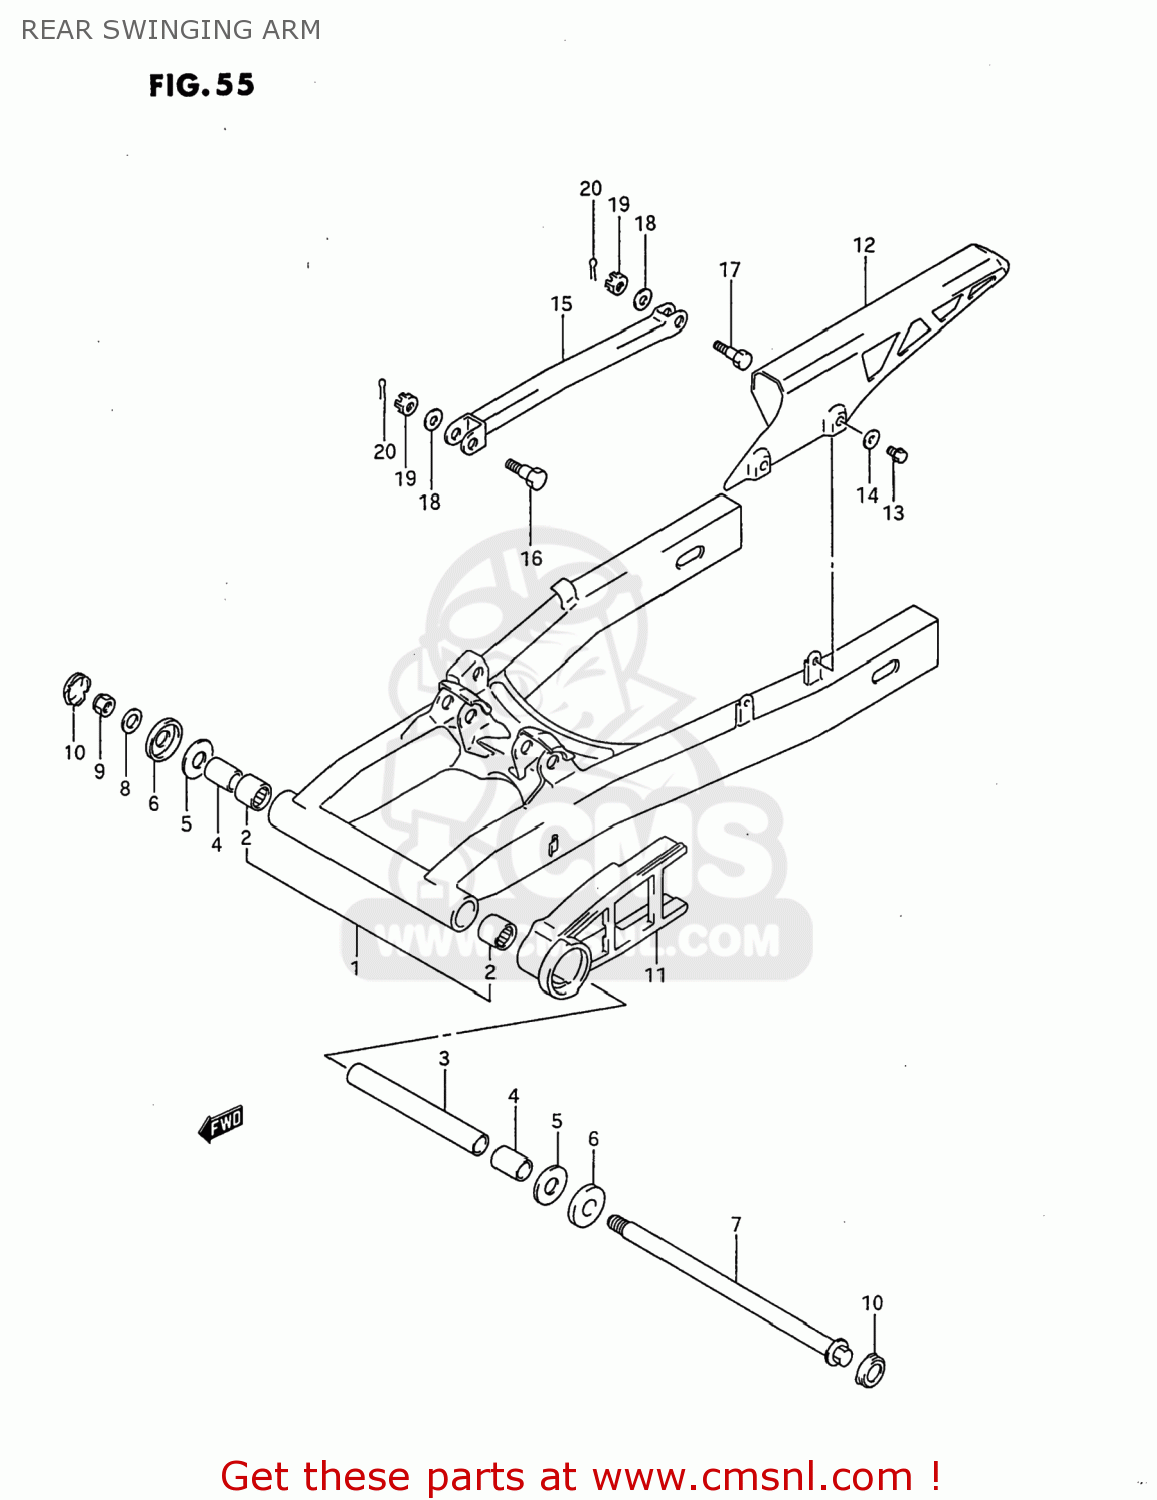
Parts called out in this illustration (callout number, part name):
1	SWINGINGARM ASSY,RR
2	BEARING(22X29X30)
3	SPACER,RR SWGARM PIVOT CTR
4	SPACER,RR SWGARM PIVOT
5	WASHER
6	COVER,RR SWGARM DUST SEAL
7	SHAFT,REAR SWING ARM PIVOT
8	WASHER(14X27X3)
9	NUT
10	CAP,SWINGINGARM PIVOT
11	BUFFER,CHAIN TOUCH DEFENSE
12	CASE,CHAIN
13	SCREW 6X12
14	WASHER
15	TORQUE LINK,REAR (BLACK)
16	BOLT(10X41)
17	BOLT(10X35)
18	WASHER (10X18X3.2)
19	NUT
20	PIN 20X20
